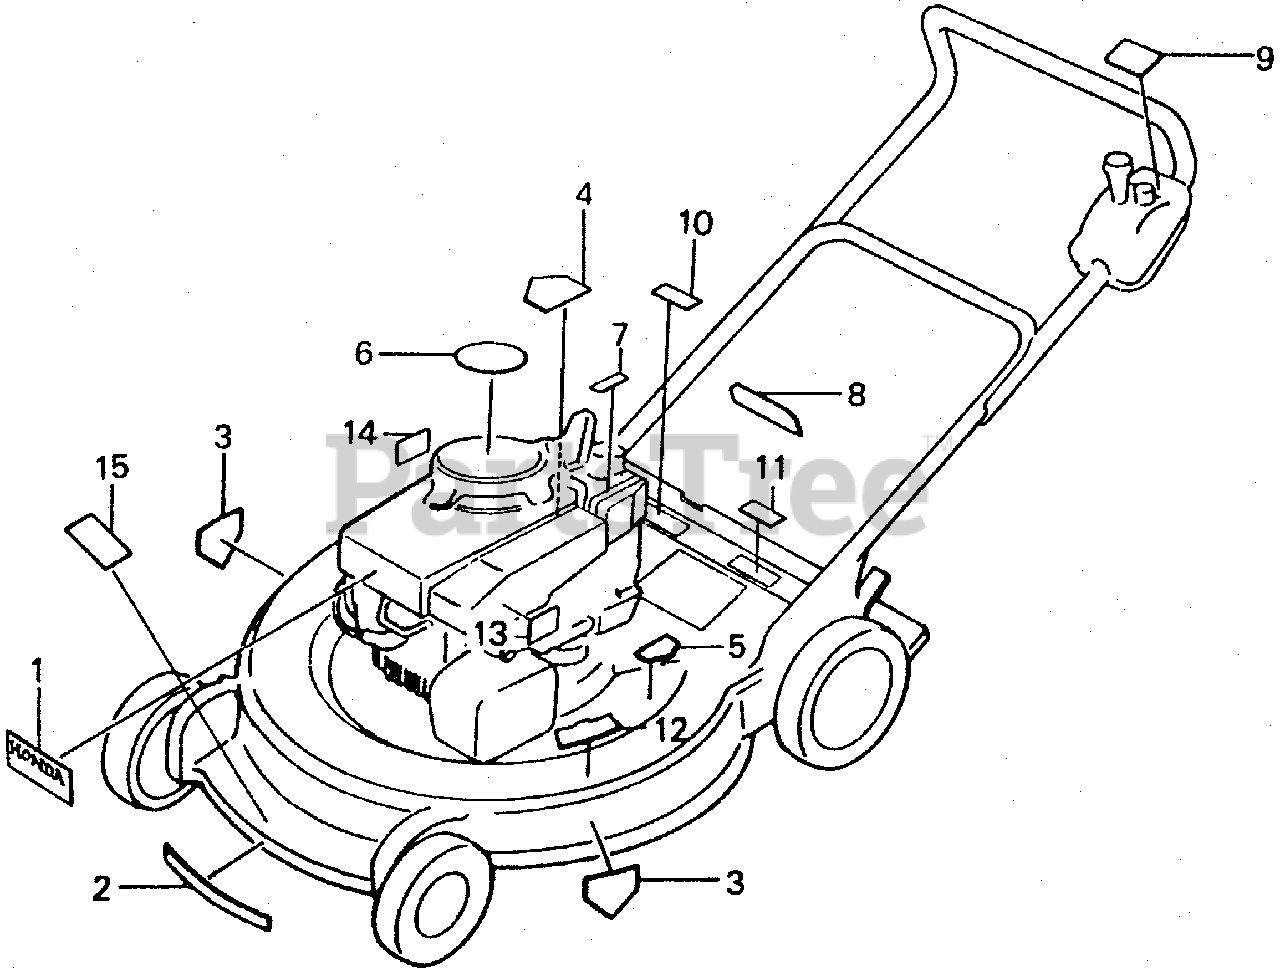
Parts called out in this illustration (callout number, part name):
1	MARK, TOP COVER (NOT AVAILABLE)
2	LABEL A, HOUSING CAUTION (ENGLISH)
3	CAUTION C, HOUSING
4	LABEL B, HOUSING CAUTION
5	LABEL, STEP POSITION (ENGLISH) (NOT AVAILABLE)
6	CAUTION, OPERATOR (ENGLISH) (NOT AVAILABLE)
7	LABEL, FUEL CAUTION (ENGLISH)
8	LABEL, DISCHARGE GUARD CAUTION (NOT AVAILABLE)
9	LABEL, CONTROL COVER CAUTION (ENGLISH) (NOT AVAILABLE)
10	MARK, DISCHARGE GUARD
11	CAUTION, BELT COVER (ENGLISH) (NOT AVAILABLE)
12	LABEL, PLUG CAUTION (ENGLISH)
13	MARK, AIR CLEANER CAUTION (NOT AVAILABLE)
14	MARK, OIL CAUTION (NOT AVAILABLE)
